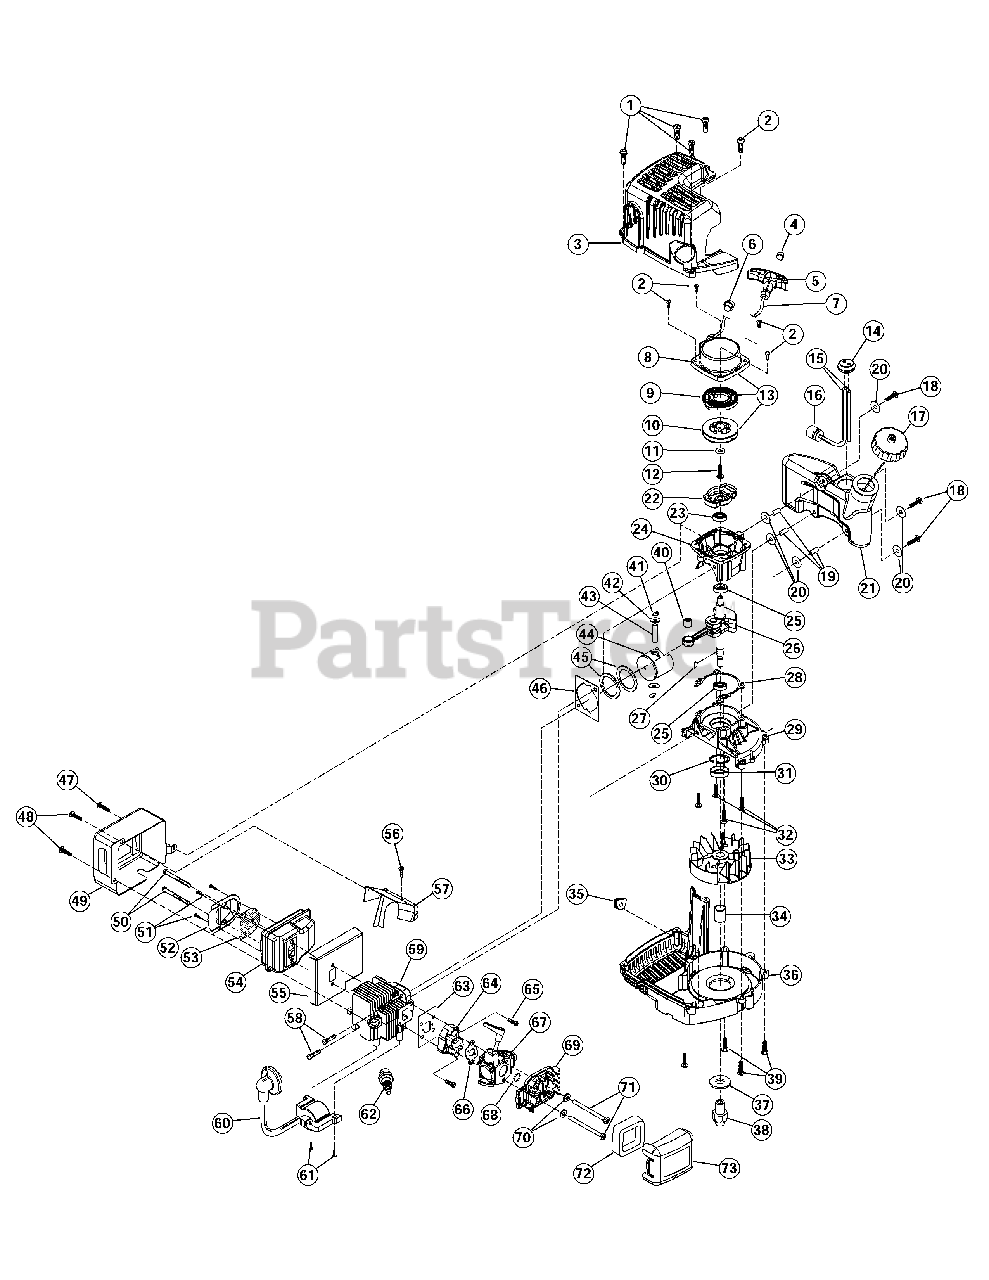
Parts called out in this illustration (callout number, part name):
1	Screw
3	Engine Cover
4	Pull Handle Bushing
5	Pull Handle
6	Rope Guide
8	Recoil Case
9	Recoil Spring
10	Recoil Pulley
11	Washer
12	Screw
13	Recoil Assembly (includes 4-12)
14	Fuel Line Grommet
15	Fuel Line
16	Fuel Filter
17	Fuel Cap
19	Spacer
20	Washer
21	Fuel Tank Assembly (includes 14-17)
22	Pawl Assembly
23	Upper Oil Seal
24	Upper Crankcase
25	Bearing
26	Keyed Powershaft Assembly
27	Flywheel Key
28	Crankshaft Gasket
29	Lower Crankcase
30	C-Clip
31	Lower Oil Seal
32	Crankshaft Screw
33	Flywheel
34	Spacer
35	Spark Wire Grommet
36	Lower Engine Cover
37	Washer
38	Impeller Nut
39	Shroud Screws
40	Needle Bearing
41	Retaining Ring
42	Piston Spacer
43	Piston Pin
44	Piston
45	Piston Ring
46	Cylinder Gasket
49	Muffler Cover
50	Muffler Bolt
51	Spark Arrestor Screw
52	Spark Arrestor Hood
53	Spark Arrestor
54	Muffler Assembly (includes 51-53)
55	Muffler Gasket
57	Cylinder Cover
58	Cylinder Bolt
59	Cylinder
60	Module
61	Module Screw
62	Spark Plug
63	Insulator Gasket
64	Insulator
65	Insulator Screw
66	Carburetor Gasket
67	Carburetor
68	O-Ring
69	Air Cleaner Assembly (includes 72 and 73)
70	Washer
71	Air Cleaner Screw
72	Air Filter
73	Air Filter Cover
